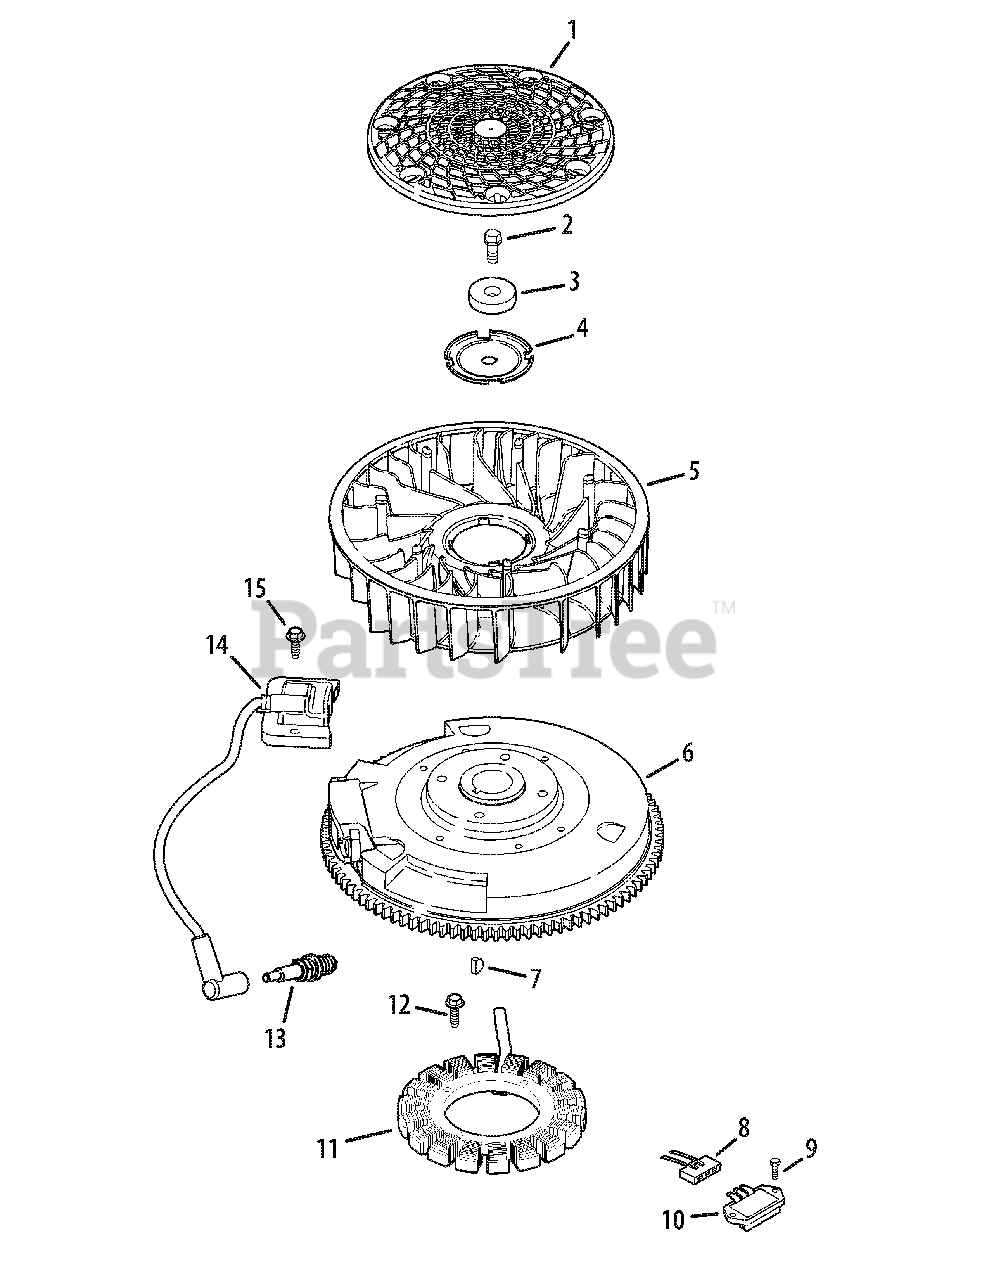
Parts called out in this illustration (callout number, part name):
1	Screen, grass
2	Screw, hex. flange M10x1.5x45
3	Washer, plain 3/8"
4	Plate, fan mounting
5	Fan
6	Flywheel
8	Connector
9	Screw, heavy hex. flange M5x0.8x16
10	Rectifier-regulator
11	Kit, 15 amp stator
12	Screw, hex. head M5x0.8x25
13	Spark plug
14	Module, ignition
15	Screw, hex. flange M5x0.8x20
